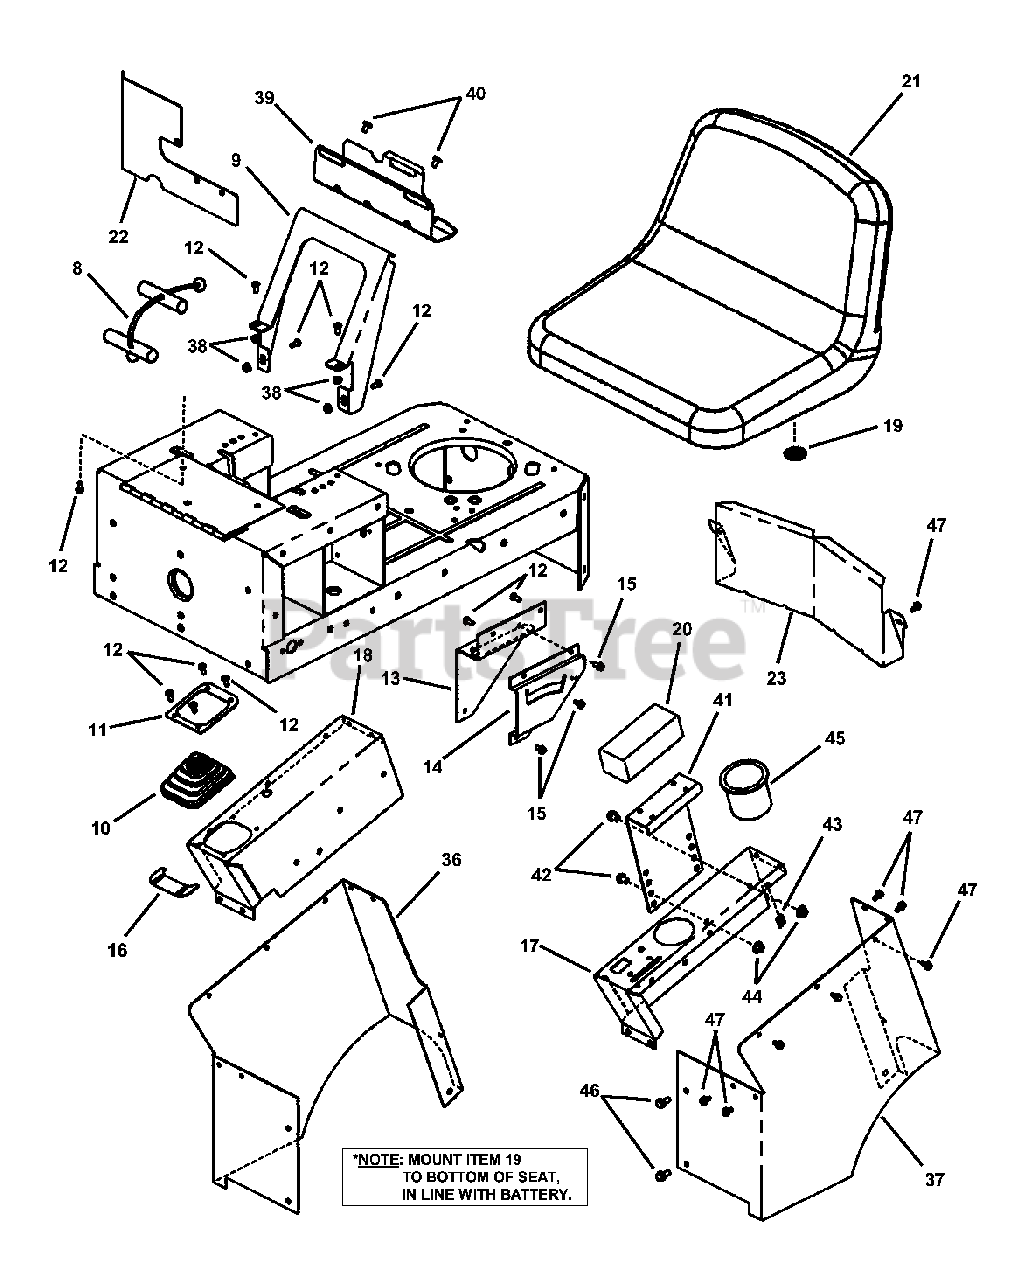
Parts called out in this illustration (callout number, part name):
8	TETHER, Seat
9	BRACKET, Fuel Tank
10	BOOT, Joystick, Rubber
11	BRACKET, Joystick Boot
12	SCREW, 1/4 x 5/8" Pan Head Self-Tap
13	BRACKET, Left Hand Tank Support
14	BRACKET, Brake/Clutch Detent
15	BOLT, 1/4-20 x 1/2" Hex Flange Lock
16	STOP, Joystick
17	PANEL, L. H. Control
18	PANEL, R. H. Control
19	BUMPER, Battery
21	SEAT (All Models)
22	HEAT SHIELD, Operator (42" Deck)
23	HEAT SHIELD, Operator (48" Deck)
36	FENDER, R.H. Steel
37	FENDER, L.H. Steel
38	NUT, 1/4-20 Hex Flange Lock
39	BRACKET, Fuel Tank
40	SCREW, 5/16-18 x 1/2" Pan Head Self-Tap (Torx)
41	BRACKET, Arm rest
42	BOLT, 5/16-18 x 1/2" Hex Flange Lock, Grade 5
43	U-CLIP, 1/4
44	NUT, 5/16-18 Hex Large Flange Center Lock
46	SCREW, 5/16-18 x 3/4" Hex Washer Self-Tap
47	SCREW, 1/4-20 x 1/2" Hex Washer Self-Tap
